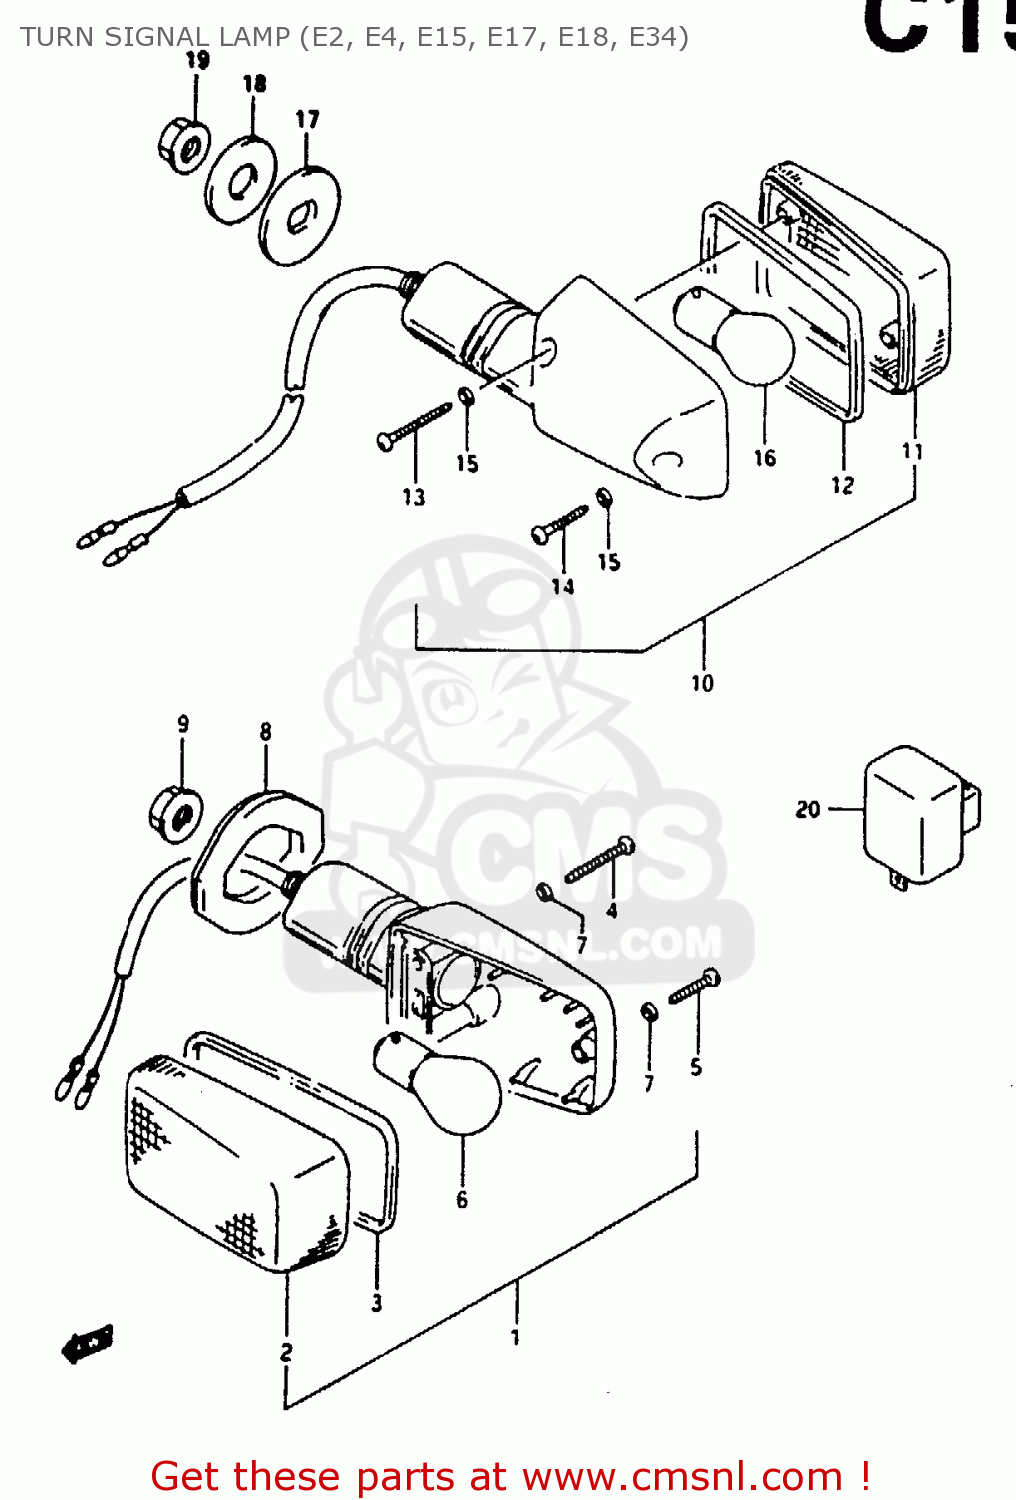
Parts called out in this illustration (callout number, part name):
1	LAMP ASSY,FR TURN SIGNAL
2	LENS
3	GASKET (NAS)
4	SCREW(3X30)
5	SCREW
6	BULB(12V21W)
7	GASKET (NAS)
8	GROMMET
9	NUT
10	LAMP ASSY,RR TURNSIGNAL
11	LENS
12	GASKET (NAS)
13	SCREW(3X30)
14	SCREW
15	GASKET (NAS)
16	BULB(12V21W)
17	SPACER,RR TURNSIGNAL
18	WASHER(10.5X30X3.2)
19	NUT
20	RELAY ASSEMBLY,TURN SIGNAL
